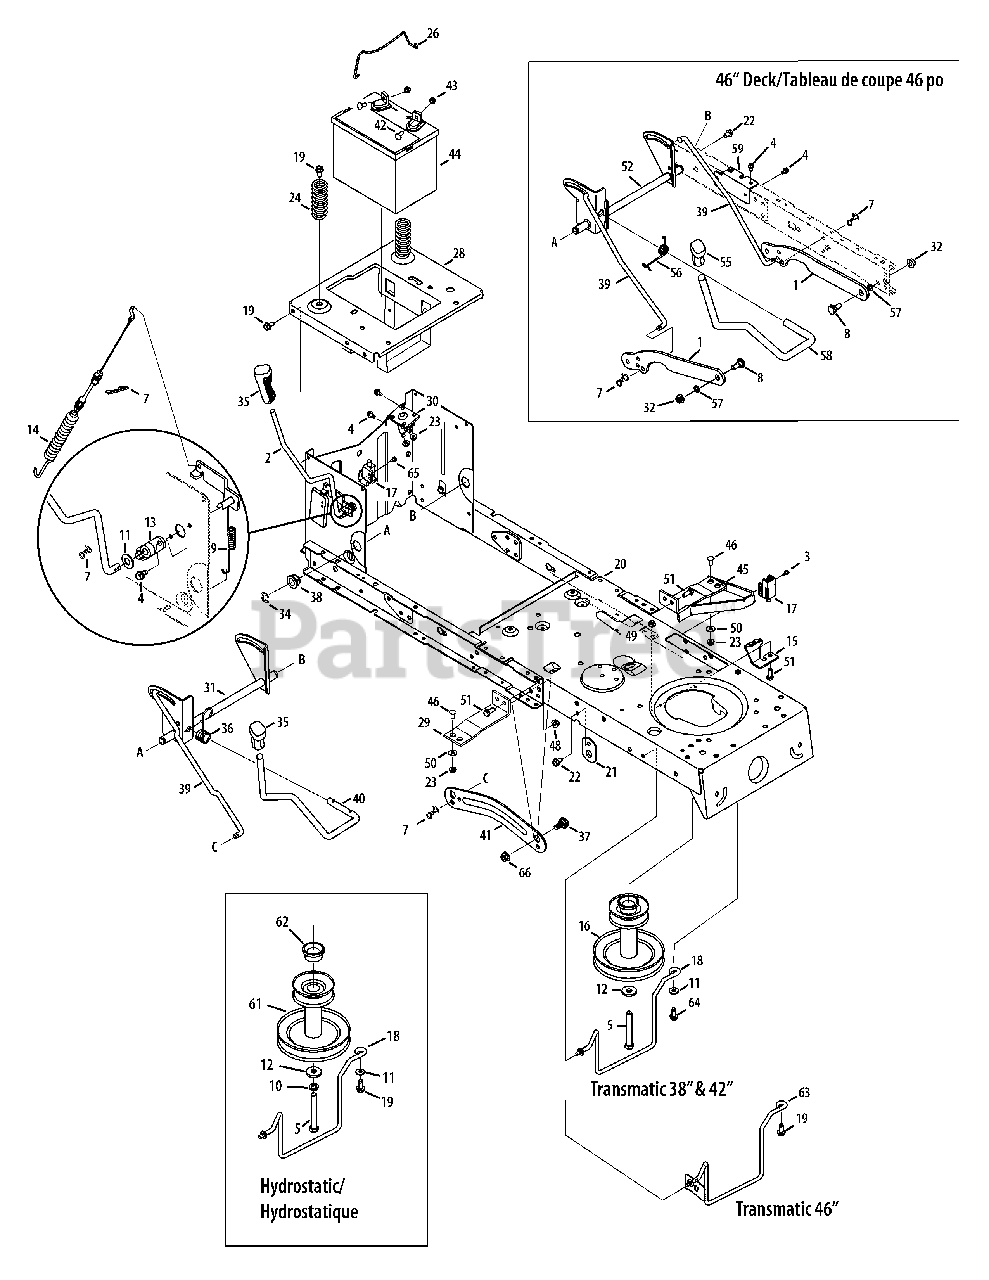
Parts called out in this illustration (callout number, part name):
1	Deck Lift Link (46")
2	PTO Handle
3	Shoulder Scr #10-16 x .50" Lg.
4	Hex Wash S-Tapp Scr 1/4-20 x .50
5	Hex Hd. Cap Scr. 7/16-20 x 3.25 Gr. 5 (38/42")
7	Bow Tie Cotter Pin
8	Shoulder Screw .5 x .270 : 3/8-16
9	Extension Spring
10	Lockwasher 7/16 ID
11	Flat Washer .385 ID x .87 OD x .06 (38/42")
12	Flat Washer .450 x 1.25 x .164
13	PTO Bearing
14	Deck Engagement Cable
15	Frame Support Bracket
16	Engine Pulley 3.39 x 6.12 dia. (38/42")
17	Interlock Switch
18	Belt Keeper Rod (38" Deck)
19	S-Tapp Scr 5/16-18 x .75
20	Frame
21	Pedal Support Bracket
22	Hex Wash HD TT Scr 5/16-18 x .625
23	Hex L-Flanged Nut 1/4-20 Gr. F, Nylon
24	Compression Spring 1.28 x 3.125
26	Battery Hold Down Rod
28	Seat Frame Bracket
29	Running Board Bracket
30	Solenoid
31	Lift Shaft (38" & 42")
32	Flange Lock-Nut 3/8-16 Gr. F, Nylon
34	"E" Ring .625 Dia.
35	Handle Grip
36	Torsion Spring (38" & 42")
37	Shoulder Screw .625 x .175, 3/8-16
38	Hex Flange Bearing .630 ID
39	Lift Rod
40	Deck Lift Handle(38"")
41	Deck Lift Arm RH
41	Deck Lift Arm LH
42	Hex Flg. Scr. 1/4-20 x .75 Gr. 5
43	Sems Hex Nut 1/4-20
44	Battery 245 CCA (Dry)
45	Support Bracket Ass’y
46	Carriage Bolt 1/4-20 x .75
48	Hex L-Flg Nut 5/16-18 Gr. F, Nylon
49	Hex L-Nut 5/16-18
50	Flat Washer .28 x .74 x .063
51	Hex Screw 5/16-18 x .75
52	Lift Shaft (46" only)
56	Torsion Spring (46")
57	Flat Washer .395 x .62 x .063
58	Deck Lift Handle (46")
59	Brace Bracket
61	Engine Pulley 3.39 x 6.12 dia. (38/42")
62	Spacer 1.0 x 1.4 x .825
63	Belt Keeper Rod (46" Deck)
64	Screw 5/16-18 x .75
65	Shoulder Scr. .342 x .335: 1/4-28
66	Flg. L-Nut 3/8-16 Gr. F
